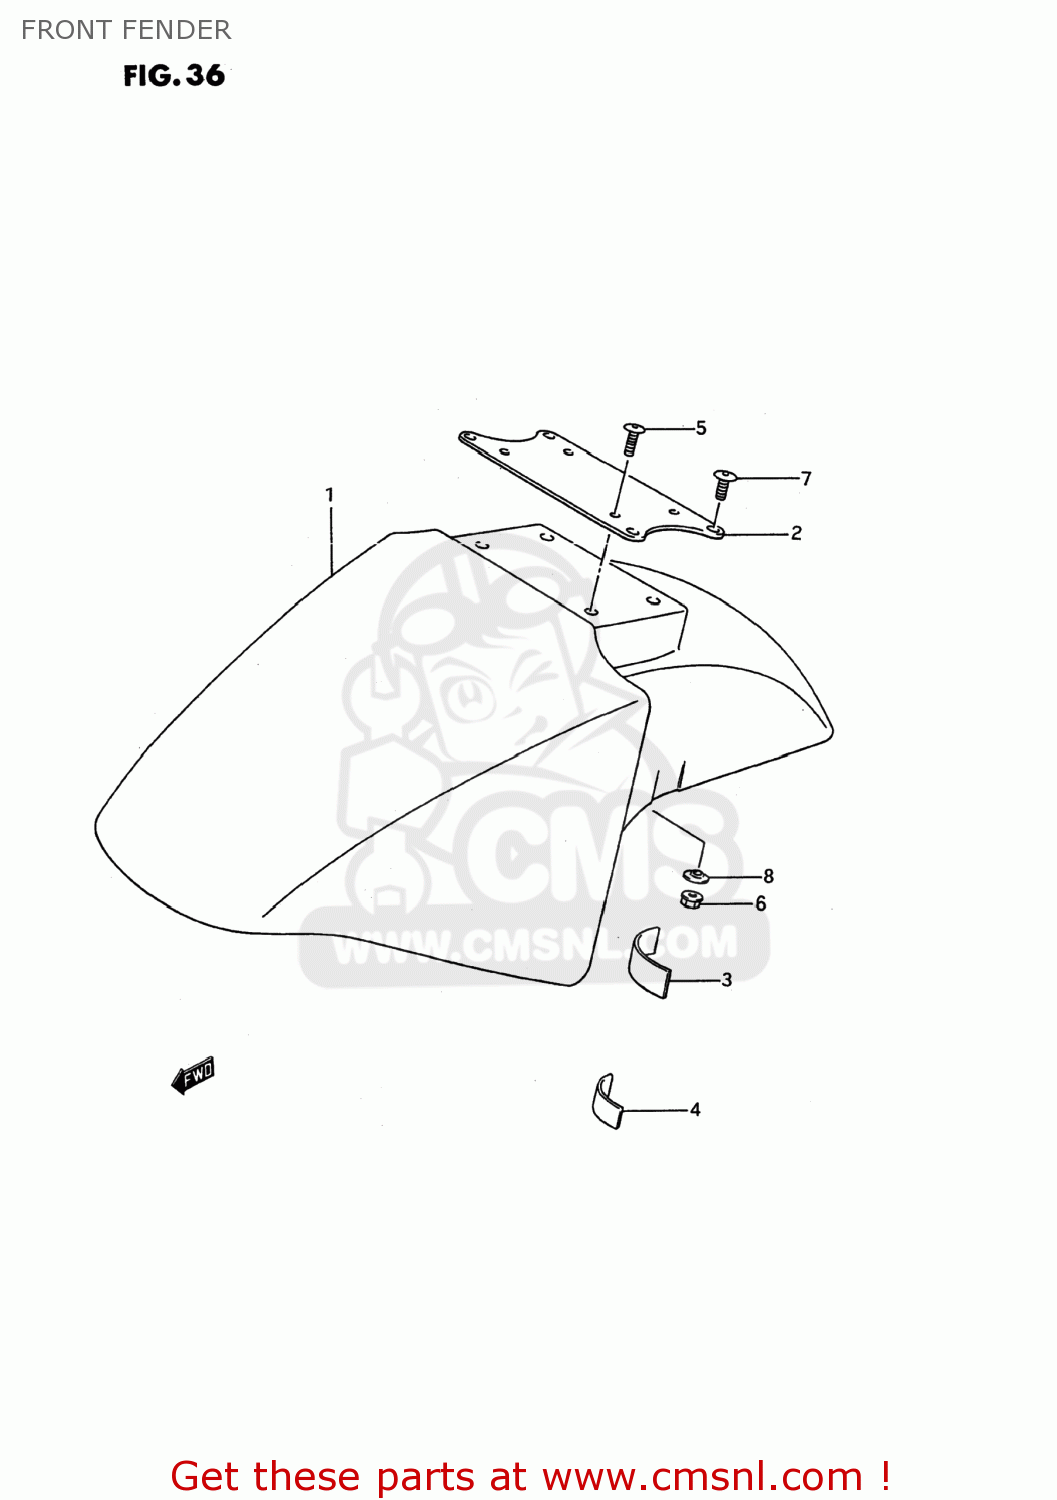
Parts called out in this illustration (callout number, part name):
1	FENDER,FRONT
2	BRACE,FR FENDER
3	CUSHION,FRONT FENDER
4	CUSHION
5	SCREW
6	NUT
7	SCREW(6X12)
8	WASHER
